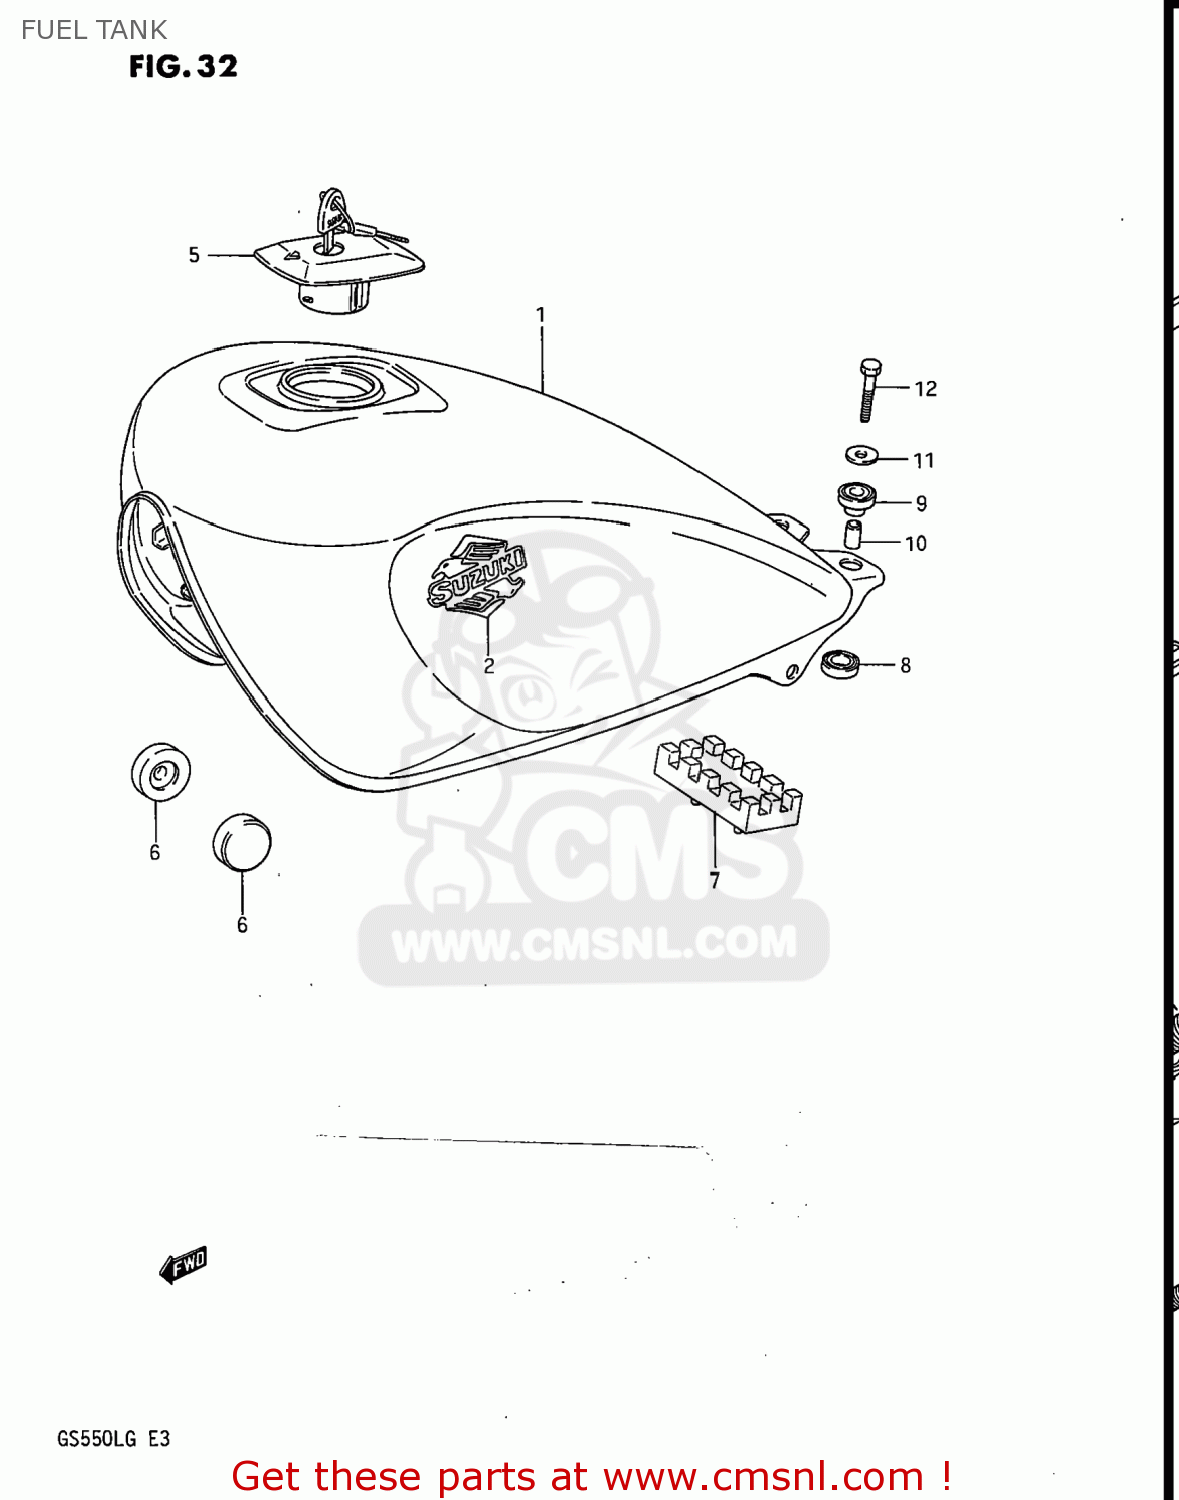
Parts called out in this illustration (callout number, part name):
1	TANK ASSEMBLY,FUEL
2	EMBLEM,FUEL TANK
3	OTHER THAN CALIFORNIA
5	CAP SET,FUEL TANK
6	CUSHION
7	CUSHION,FUEL TANK
8	CUSHION
9	CUSHION
10	SPACER
11	WASHER (6.5X24X1.6)
12	BOLT
